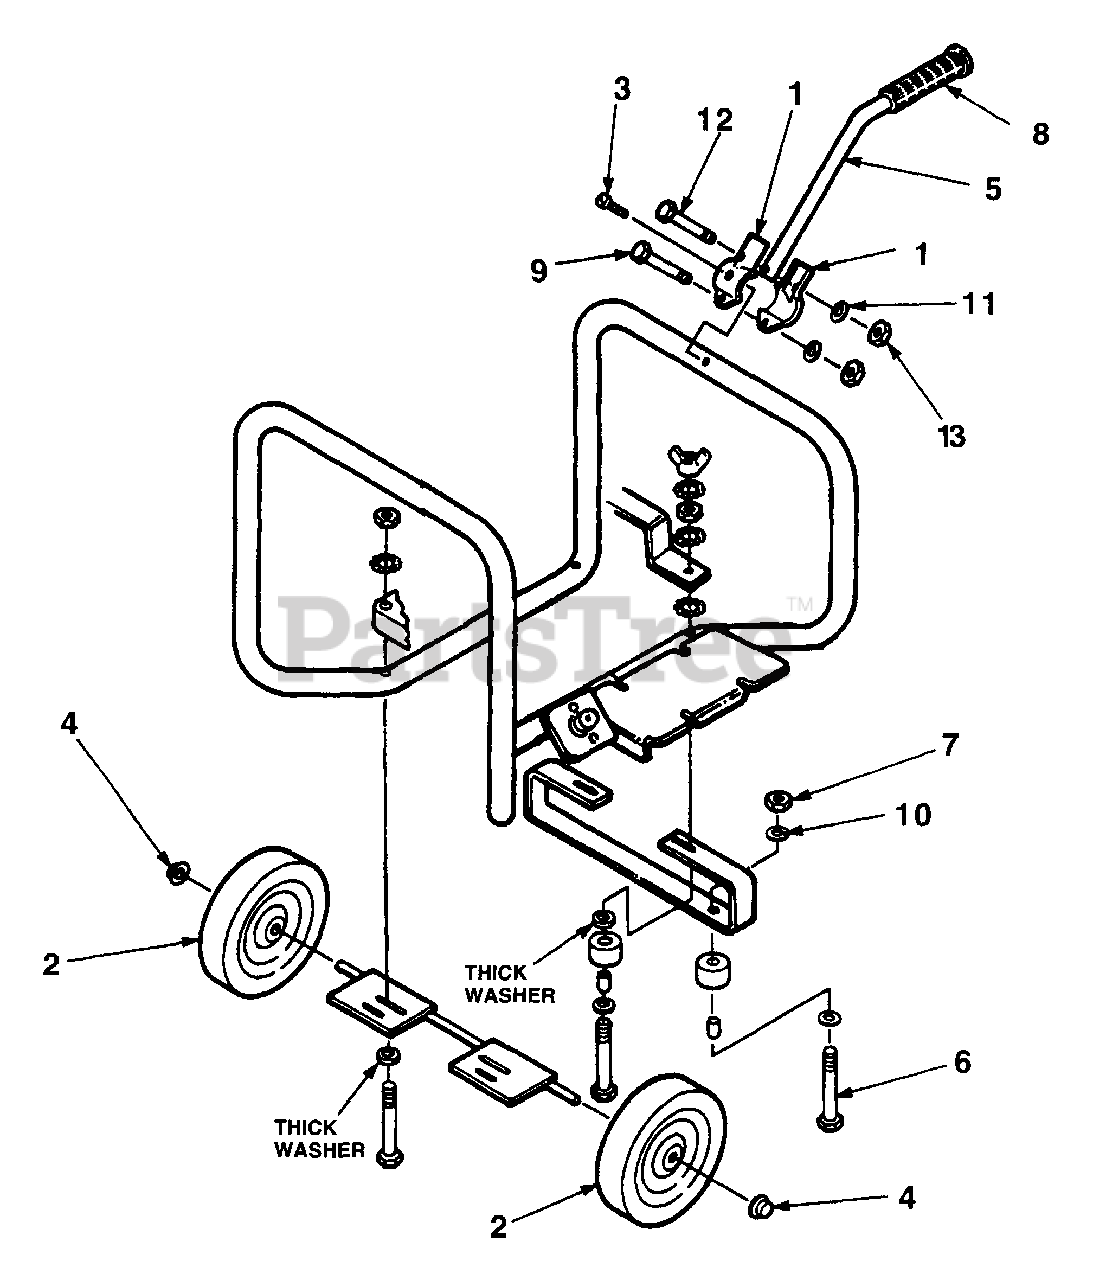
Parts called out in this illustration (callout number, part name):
1	Clamp, Handle
2	Wheel & Tire
3	Screw. Thd. Form. (#10 x 3/4")
6	Screw, Hex Hd. (5/16-18 x 1 1/4")
7	Nut, Hex (5/16-18)
8	Grip
9	SCREW- Hex Hd. (1/4-20 x 1")
10	Washer, Lock (5/16")
11	Washer, Lock (1/4")
12	Screw, Hex Hd. (1/4-20 x 1 1/2")
13	Nut, Hex (1/4-20)
